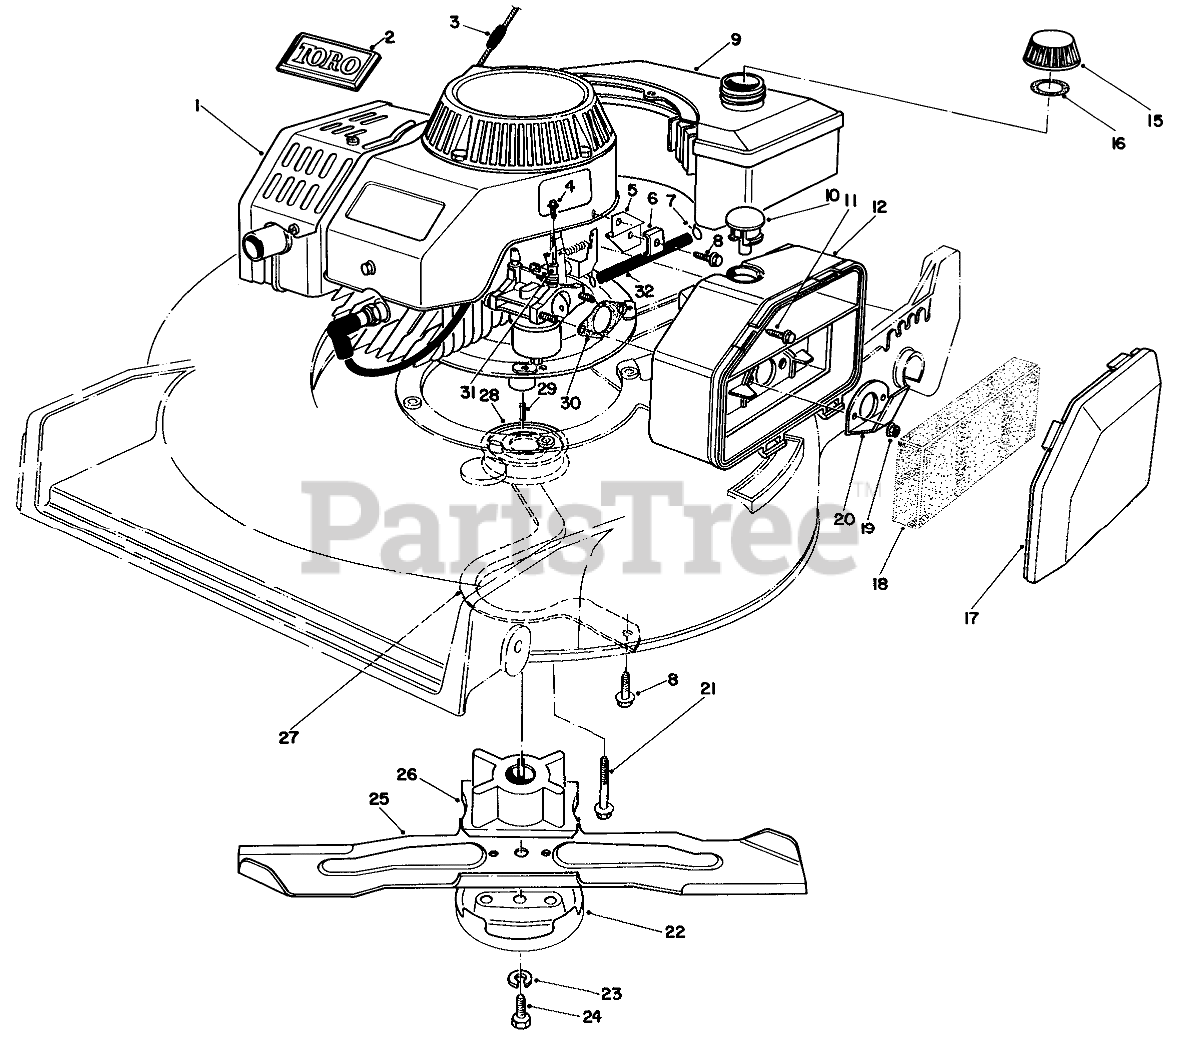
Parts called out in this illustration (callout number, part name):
1	Engine (Incl. Ref. #1)
2	TORO LOGO PLT
3	STOP-ROPE
4	TAPPING SCREW
5	Carrier-Cable
6	CLAMP-CABLE
7	CLAMP-HOSE
8	Screw
9	Gas Tank Assembly
10	Plug-Button
11	Screw-Hex Head
12	AIR CLEANER
15	GAS CAP ASM
16	GAS CAP GASKET
17	AIR CLEANER COVER
18	FILTER
19	M6 X 1 LOCKNUT
20	SPIT BACK DEFLECTOR
21	SCREW-HHF
22	Anti Scalp Cup
23	WASHER-LOCK
24	SCREW-BLADE
25	BLADE-21in
26	Retainer Blade
27	BELT GUIDE
28	PULLEY-DRIVER
29	KEY-SQUARE
30	GASKET-AIR CLEANER
31	CHOKE LEVER
32	FUEL LINE
